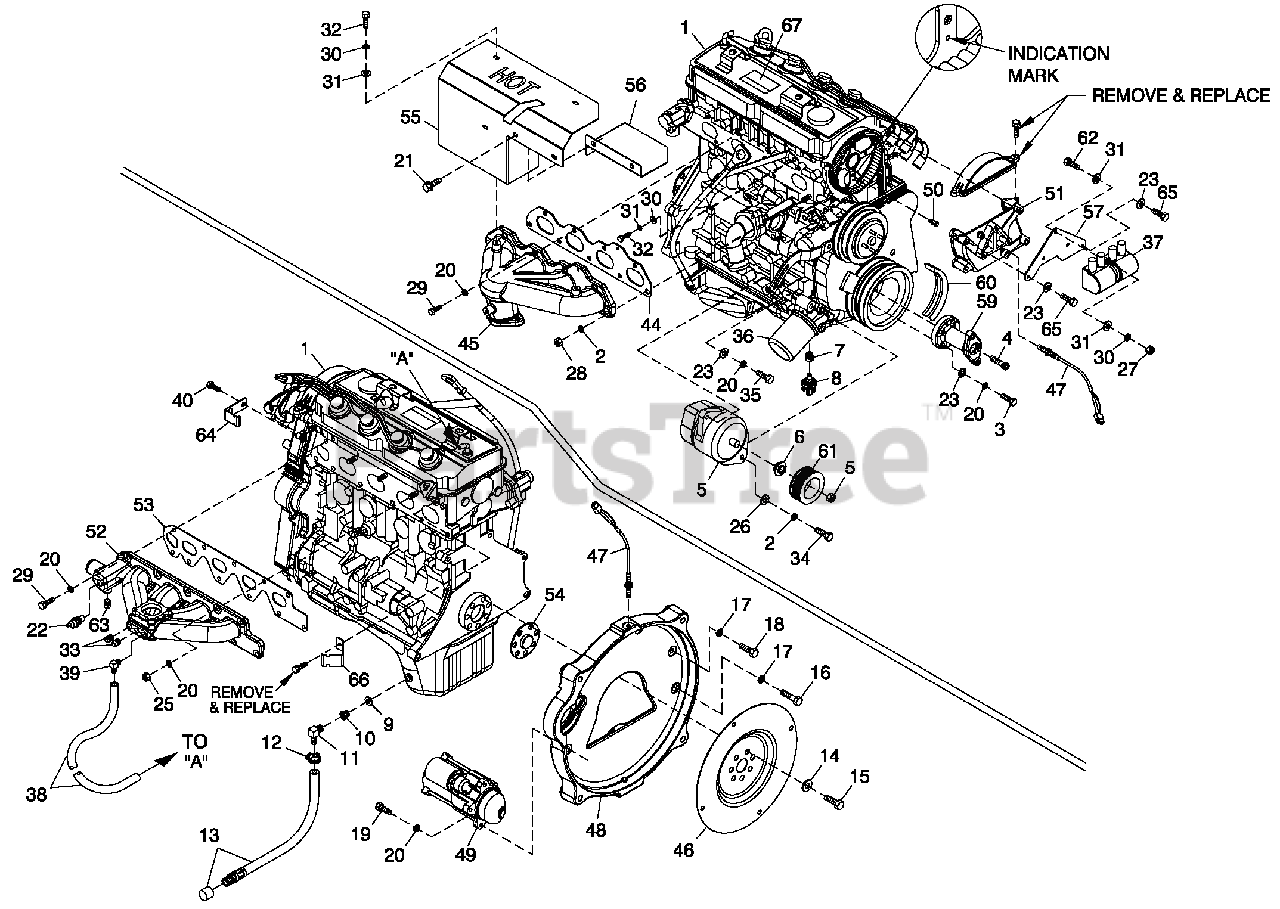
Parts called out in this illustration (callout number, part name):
1	ENGINE 2.4L MITSUBISHI 4G64
2	WASHER LOCK M10
3	SCREW HHC M8-1.25X35G8.8
4	SCREW SHC M14-1.5 X 35 G10.9
5	ALTERNATOR DC W/OUT PULLEY
6	SPACER DC ALTERNATOR PULLEY
7	ADAPTOR 1/ 8 NPTF TO 1/8 BSPT
8	SWITCH OIL PRESSURE 10 PSI 2 POL (R-PANEL)
9	WASHER NYLON .565
10	ADAPTER M14-1.50X 3/8 NPT
11	BARBED EL 90 3/8 NPT X 3/8
12	CLAMP HOSE .38-.87
13	HOSE DRAIN ASSY 28"
14	WASHER FLAT .531 ID X 1.062 OD
15	SCREW HHC M12-1.25 X 20 G10.9
16	SCREW HHC M10-1.25 X 45 G8.8
17	WASHER SHAKEPROOF EXT 7/16 STL
18	SCREW HHC M10-1.25 X 30 G8.8
19	SCREW SHC M8-1.25 X 30 G12.9
20	WASHER LOCK M8-5/16
21	SCREW THF M6-1 X 16 N WAZ/JS
22	SWITCH HI-TEMP 245D X 3/8 NPT (R-PANEL)
23	WASHERFLAT 5/16-M8ZINC
25	NUT HEX M8-1.25 G8 CLEARZINC
26	WASHERFLAT 3/8-M10ZINC
27	NUT HEX M6X 1.0 G8 YEL CHR
28	NUT HEX M10-1.25 G8 YEL CHR
29	SCREW SHC M8-1.25 X 25 G12.9
30	WASHER LOCK M6-1/4
31	WASHERFLAT 1/4-M6 ZINC
32	SCREW HHC M6-1.0X 12 G8.8
33	PLUG STD PIPE 1/4 STEEL SQ HD
34	SCREW HHC M10-1.5X60G8.8
35	SCREW HHC M8-1.25 X 25 G10.9
36	OIL FILTER G2 ENGINE
37	COIL PACK
38	HOSE 3/8 ID SINGLE BRAID (15" LG)
39	BARBED EL 90 1/4 NPT X 3/8
40	SCREW HHC M6-1.0X25G8.8
44	GASKET EXHAUST MANIFOLD
45	EXHAUST MANIFOLD G2 (MACHINE) (25KW, 35KW & 45KW)
46	FLEX PLATE 2 POLE 2.4LG2
47	ASSY MAGPICKUP(3/8-24 MALE)
48	ADAPTER ENGINE 2.4L MACHINE
49	STARTER, 12 VOLT
50	CAM SENSOR PIN ASSY
51	COVER CAM GEAR G2 REWORKED
52	MANIFOLD INTAKE
53	GASKET INTAKE MANIFOLD
54	SPACER 2.4L G2 FLEX PLATE
55	SHIELD HEATG2
56	SHIELD HEATSML
57	BRACKET COIL PACK
59	ADAPTER 2.4L CRANKSHAFT MACH
60	POLY V-BELTG2 (3600 RPM)
61	PULLEY DC ALTERNATOR (3600 RPM)
62	SCREW HHC M6-1.0 X 35 G8.8 BLK
63	PLUG STD PIPE 3/8 STEEL SQ HD
64	BRACKET, SIGNAL CONDITIONER
65	SCREW HHC M8-1.25X70G8.8
66	BRACKET SIGNAL CONDITONER
67	DECAL EMISSION CTRL INFO 2.4L
